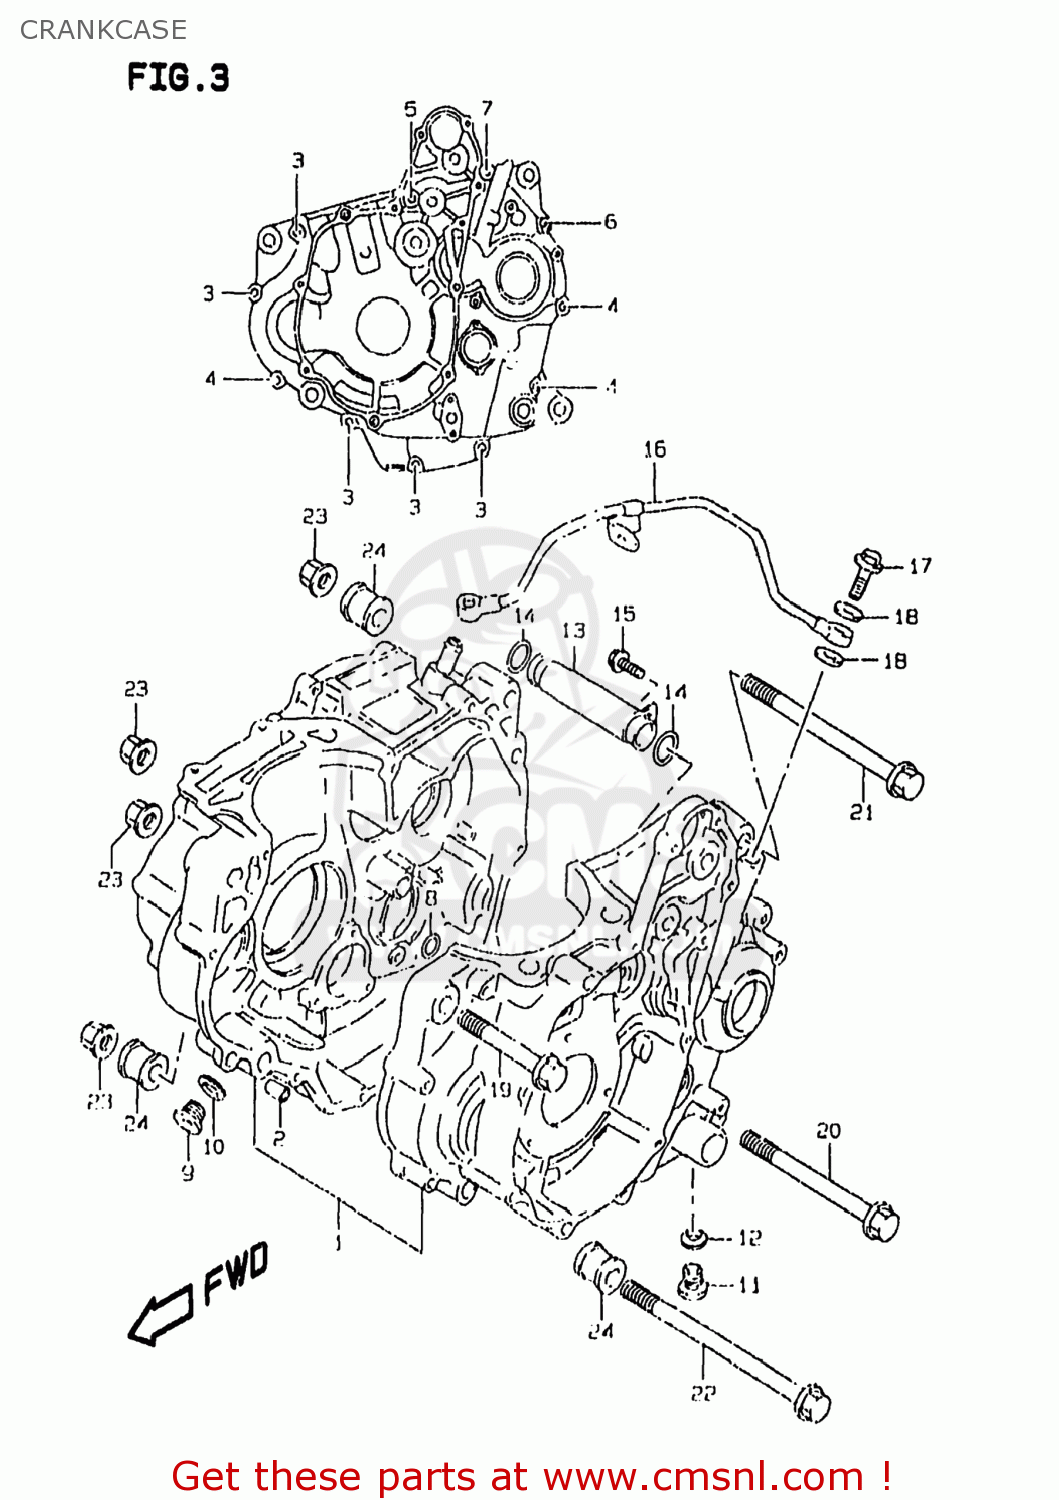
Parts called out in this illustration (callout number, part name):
1	CRANKCASE SET
2	PIN
3	BOLT
4	BOLT
5	BOLT
6	BOLT
7	BOLT
8	O RING(D:1.9,ID:12.6)
9	PLUG,14X12
10	GASKET(13.8X18.8X4.8) (NAS)
11	BOLT
12	GASKET(12.1X16.2X3.7) (NAS)
13	PIPE,T/M OIL INNER
14	O RING(D:2.4,ID:15.8)
15	BOLT
16	PIPE,MISSION OIL OUTER
17	BOLT UNION
18	GASKET 8.2X14X1 (NAS)
19	BOLT 10X85
20	BOLT(10X101.5)
21	BOLT(10X115)
22	BOLT(10X143)
23	NUT
24	SPACER,ENGINE MOUNTING
